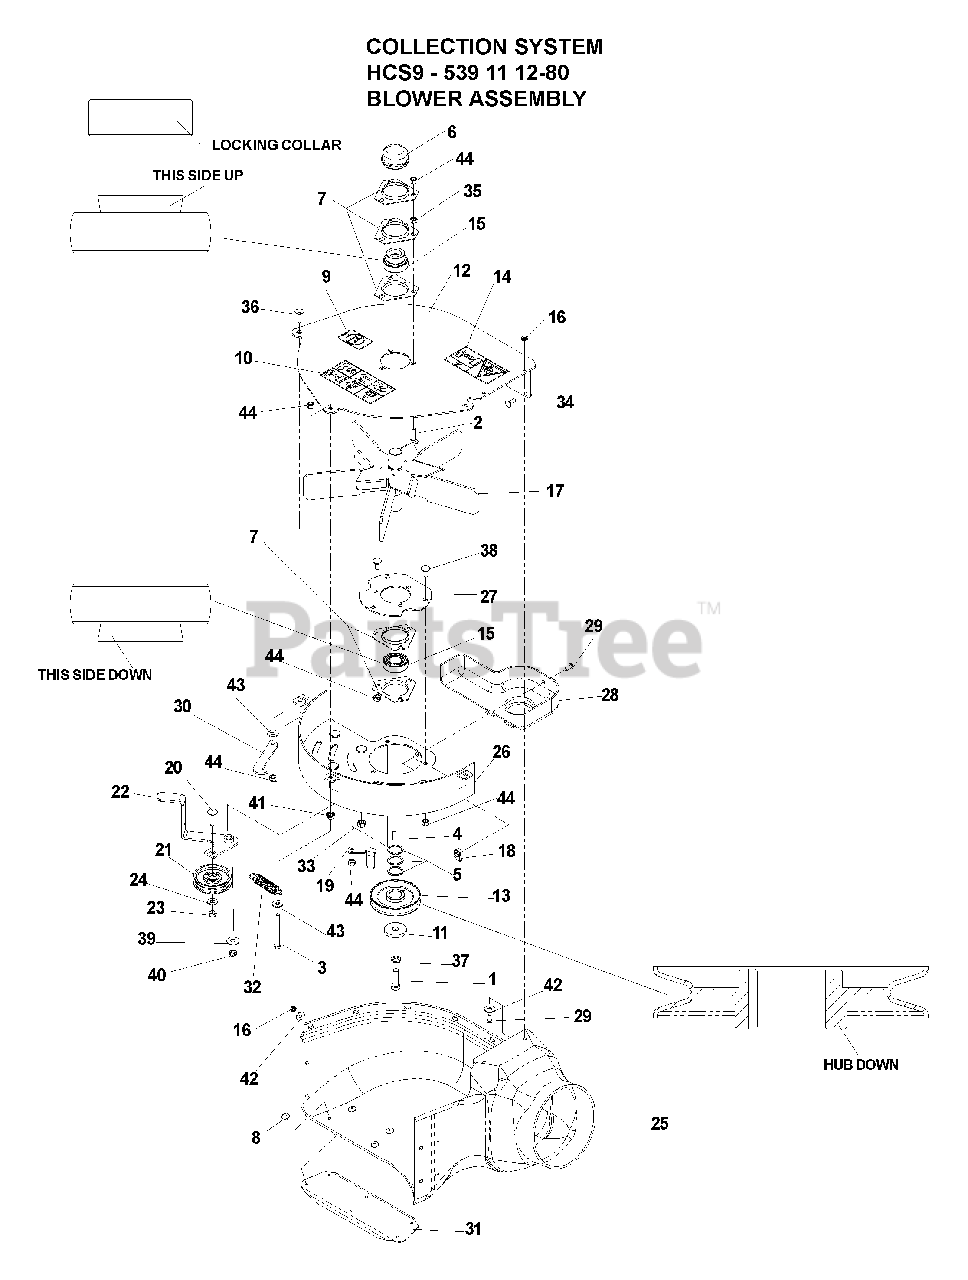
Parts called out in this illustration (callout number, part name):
1	HCS, 7/16-20 X 1 1/2, GR5
2	RHSNB, 5/16-18 X 1 1/4, GR5
3	HCS, 5/16-18 X 2 3/4, GR5
4	KEY, 1/4 SQ X 3/4
6	CAP, GREASE
7	BUSHING, FLANGE
8	RIVET, 3/16 X 1/4
9	DECAL, EURO NO STEP
10	DECAL, EURO WARNING
11	WASHER, 15/32
12	FAN COVER W/DECALS
14	DECAL, EURO IMPELLER
16	NUT, 1/4-20, THIN NYLOC
18	U TYPE RETAINER, 1/4C
19	BELT GUIDE
20	RHSNB, 3/8-16 X 1 1/4, GR5
23	NUT, 3/8-16, THIN NYLOC
24	WASHER, 3/8
25	BLOWER HOUSING
26	FLOOR WELDMENT
27	BEARING PLATE
28	PULLEY SHIELD
29	SCREW, 1/4-20 X 5/8
30	KEEPER, IDLER
31	BLOWER SUPPORT
33	NUT, 3/8-16, NYLOC
34	RHSNB, 1/4-20 X 3/4, GR2
35	NUT, 5/16-18
36	RHSNB, 5/16-18 X 1, GR5
37	LOCKWASHER, 7/16
38	RHSNB, 5/16-18 X 3/4, GR5
39	WASHER, 3/8
40	NUT, 3/8-16, CENTERLOCK
41	NUT, 5/16-18, WHIZLK
42	WASHER, 1/4
43	WASHER, 5/16
44	NUT, 5/16-18, NYLOC
539111280	Blower Assembly Collection System
